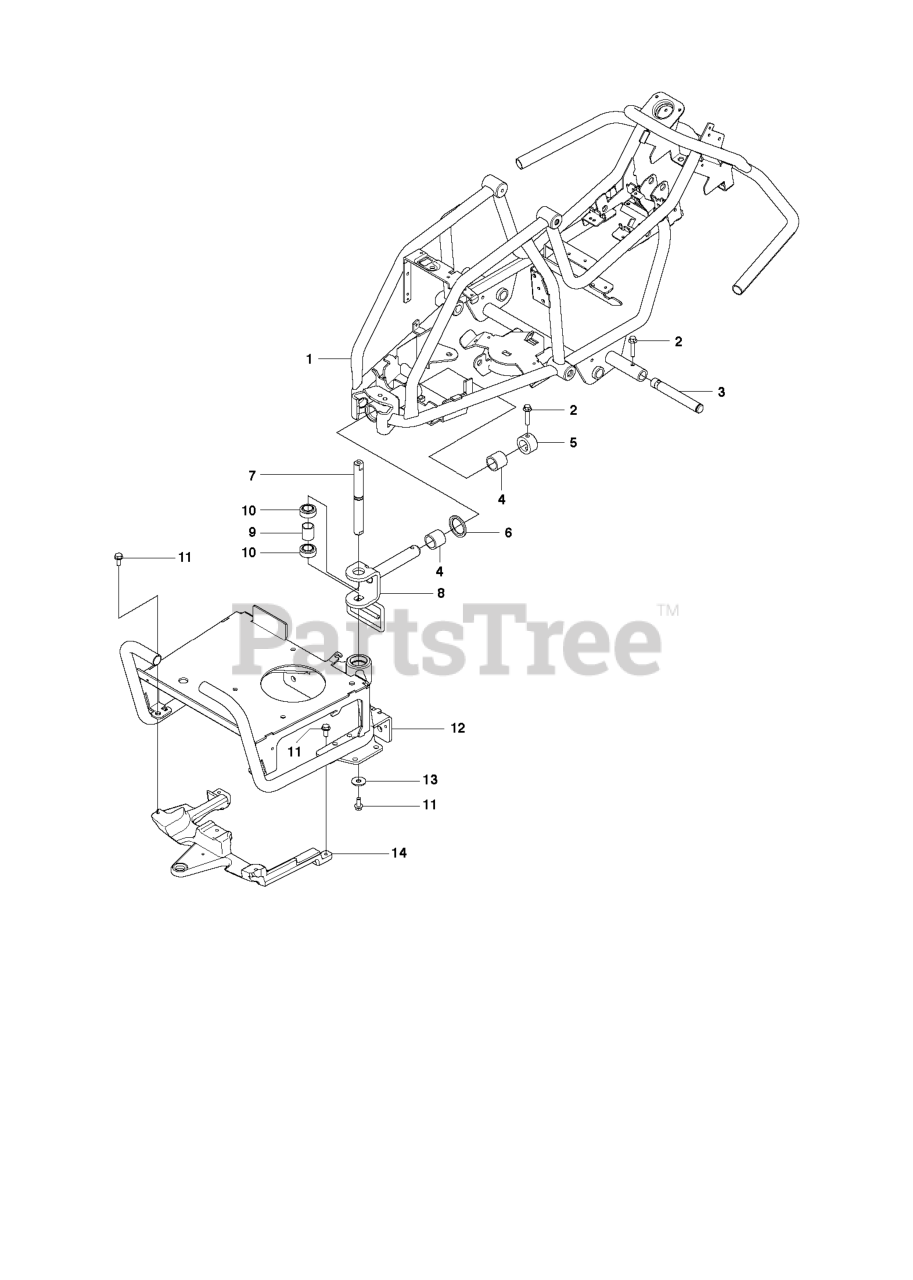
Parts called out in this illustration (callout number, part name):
2	BOLT FLANGE - M8X40\
4	BUSHING
5	STOP SLEEVE
